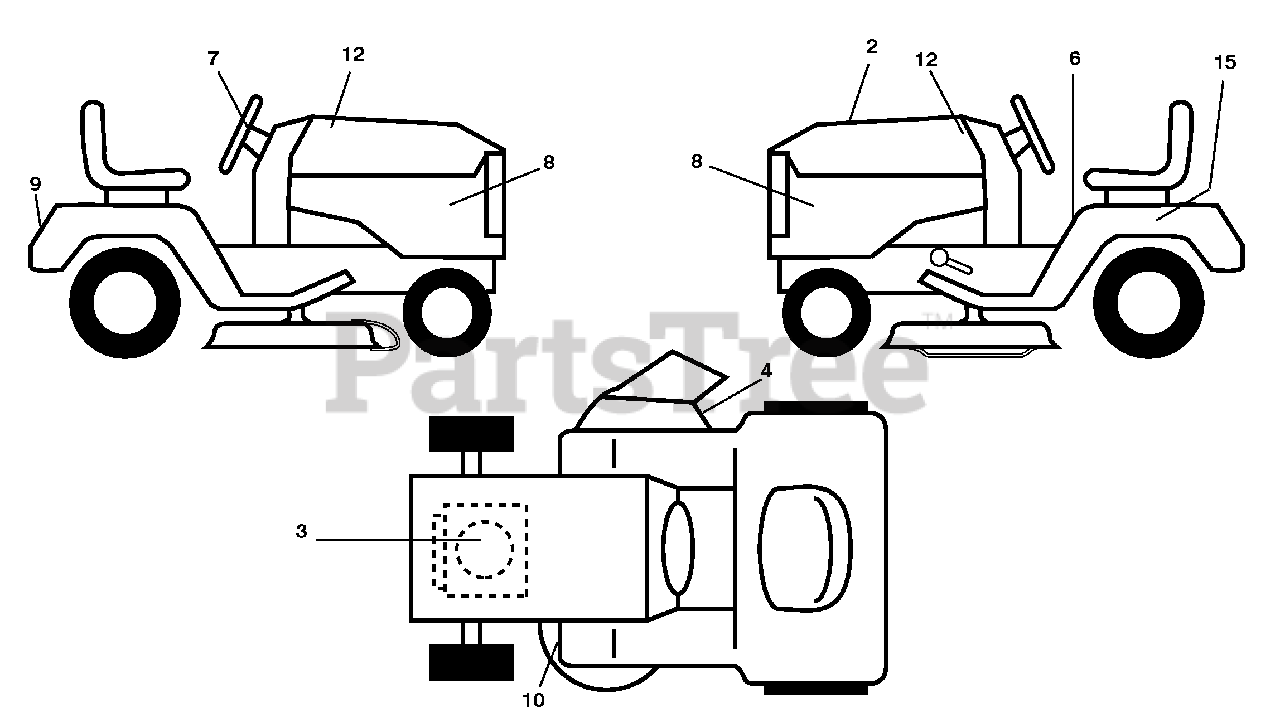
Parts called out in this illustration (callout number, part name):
1	Decal, Warning
2	Decal, Replacement
3	Decal, Engine HP
4	Decal, Warning
6	Decal, Fender Warning
7	Decal, Ins Str Wh
8	Decal, Side Panel
9	Decal, Fender
10	Decal, V-Belt Sch.
12	Decal, Hood
15	Decal, Caution, Battery
15	Pad Foot Rest RH
15	Pad Foot Rest LH
15	Decal, Handle Lft Height Adj.
15	Manual, Operator's, English/French
15	Manual, Operator's, Spanish
15	Manual, Parts, English/French
